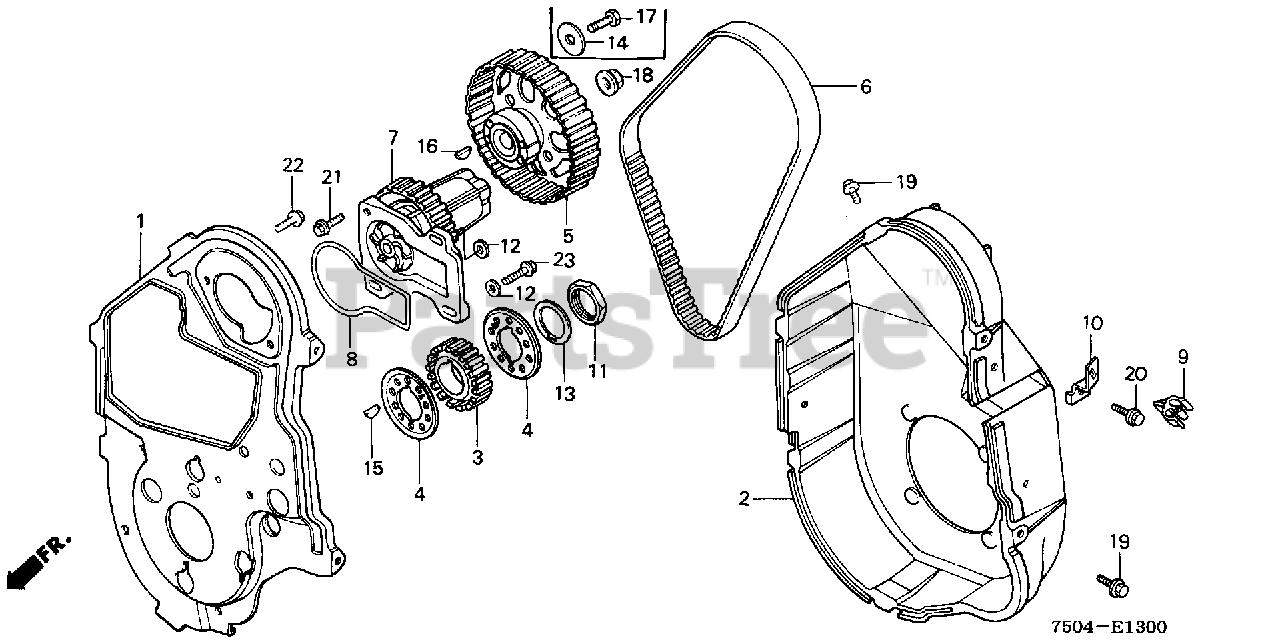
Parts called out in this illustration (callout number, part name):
1	COVER B, TIMING BELT
2	COVER A, TIMING BELT
3	PULLEY, TIMING
4	FLANGE, TIMING PULLEY
5	CAM AND PULLEY KIT
5	CAMSHAFT
5	PULLEY, CAMSHAFT
6	BELT, TIMING
7	WATER PUMP
8	O-RING, WATER PUMP
9	CLIP, RECEIVER PIPE (NOT AVAILABLE)
10	BRACKET, IGNITION WIRE CLIP
11	NUT, LOCK (30MM)
12	WASHER, PLAIN (6.5X15)
13	WASHER, LOCK (30MM)
14	WASHER, PLAIN (6MM)
14	WASHER, WHEEL (6MM)
15	KEY, SPECIAL WOODRUFF (25X18)
16	KEY, CAM PULLEY
16	KEY, WOODRUFF (16X12)
17	BOLT, HEX. (6X16)
18	NUT, FLANGE (10MM)
19	BOLT, FLANGE (6X10)
20	BOLT, FLANGE (6X12)
21	BOLT, FLANGE (6X22)
22	BOLT, FLANGE (6X12)
23	BOLT, FLANGE (6X22)
